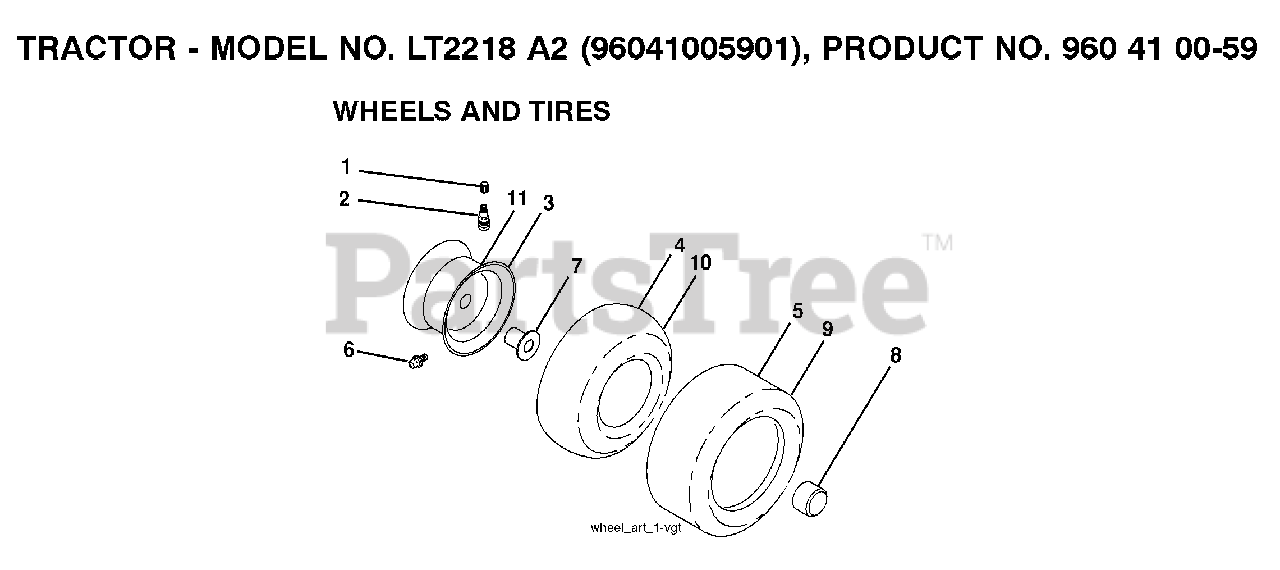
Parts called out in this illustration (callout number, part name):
1	VALVE CAP
2	VALVE STEM LT
3	RIM ASM 6" FRONT SILVER
4	TUBE.5.3/4.5/6
5	TIRE HEAVY DUTY
6	FITTING LT
7	BEARING T
8	CAP, AXLE BLK
9	TIRE.TS.20X10-8
10	TUBE
11	RIM ASM 8" REAR SILVER
